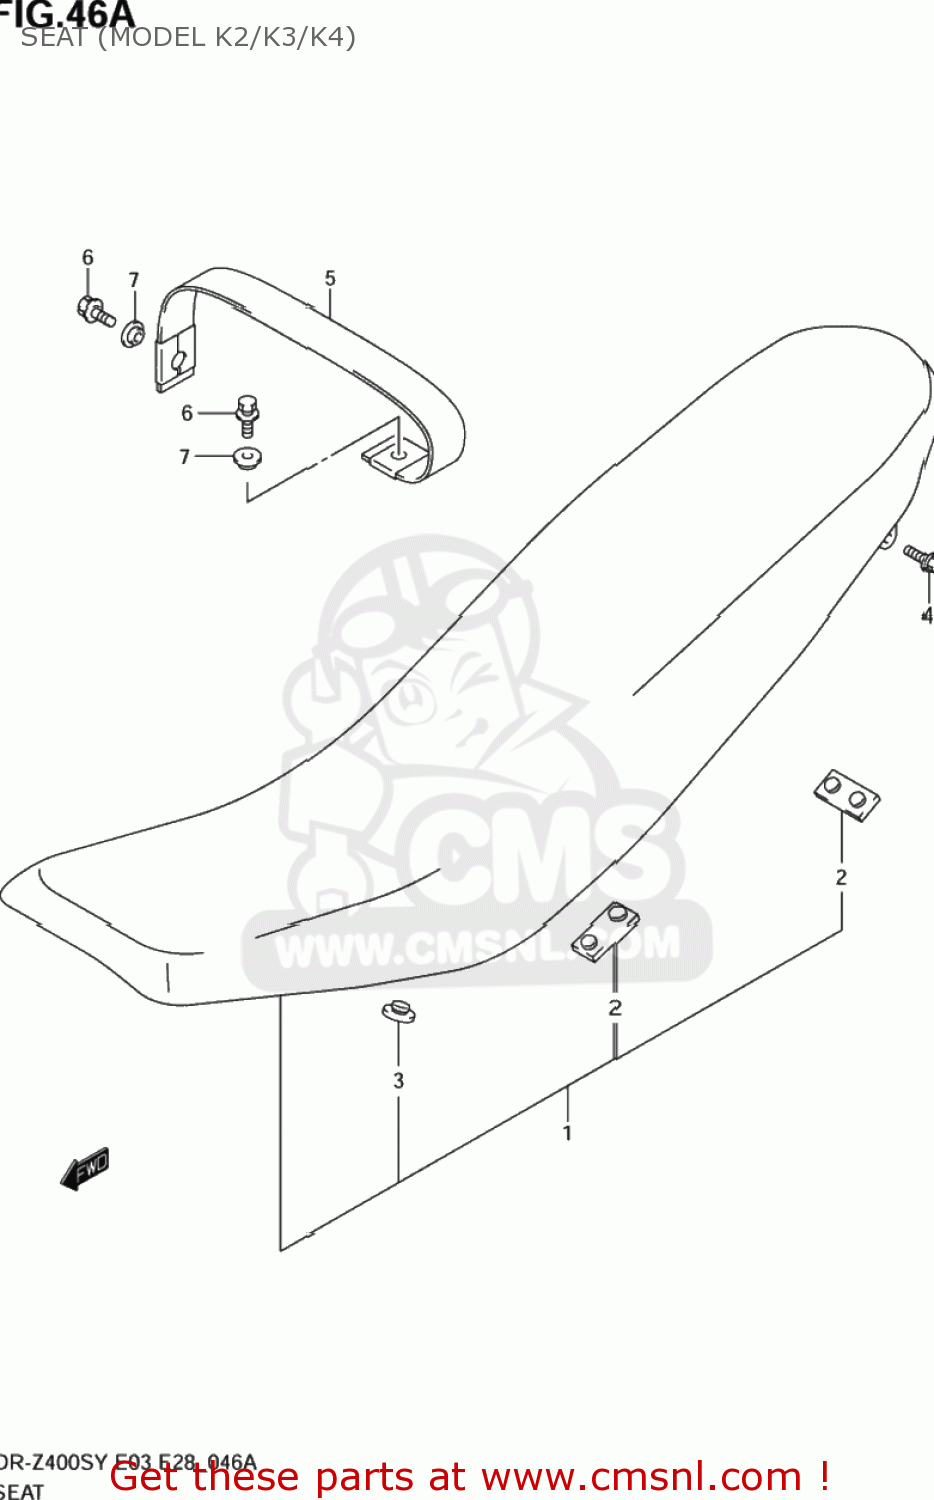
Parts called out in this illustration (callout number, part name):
1	SEAT ASSY(BLACK)
2	CUSHION,SEAT(40X20X6)
3	CUSHION
4	BOLT
5	BAND ASSY,SEAT
6	BOLT(6X25)
7	WASHER
